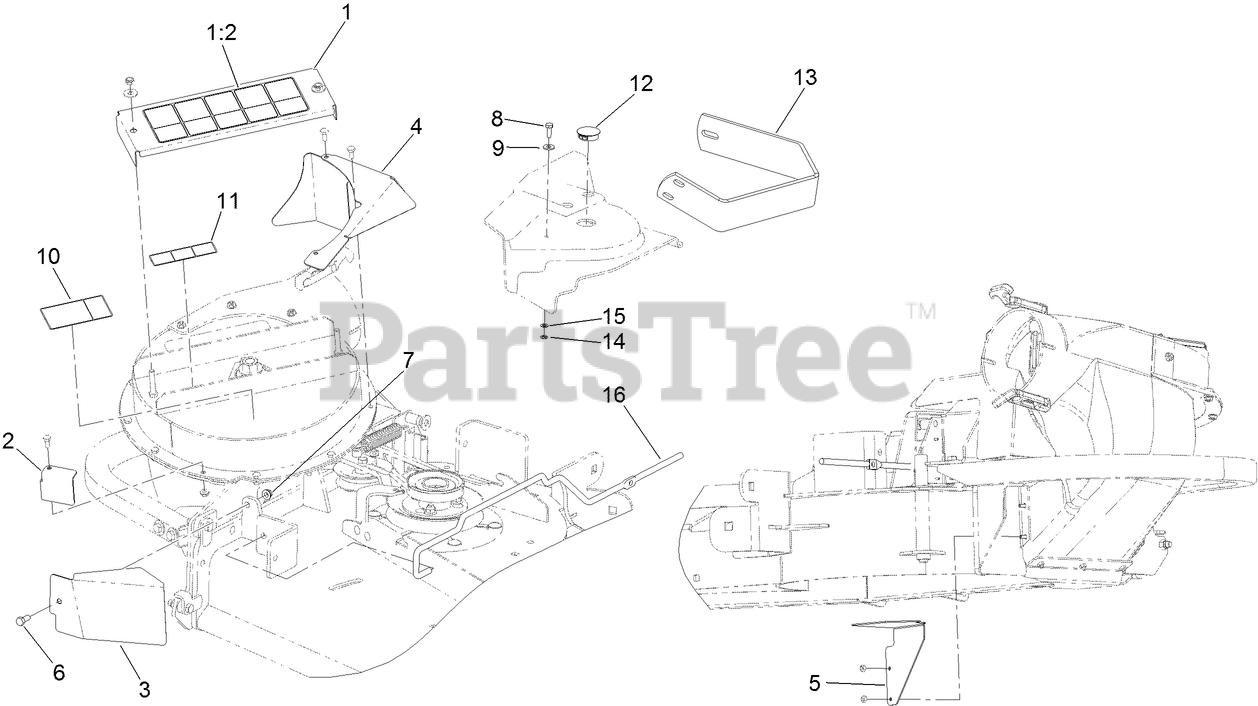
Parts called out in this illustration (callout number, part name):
1	COVER-BEARING
1:2	DECAL-DANGER
2	GUARD-LEFT
3	GUARD-FRONT
4	GUARD-TOP
5	GUARD-LOWER
6	SCREW-HH
7	NUT-HF
8	SCREW-HH
9	WASHER-FLAT
10	DECAL-WARNING
11	DECAL-MISSING, COVER
12	PLUG-PLASTIC
13	GUARD-MUFFLER
14	NUT-RETAINER
15	WASHER-FLAT
16	ROD-SUPPORT, LOWER
